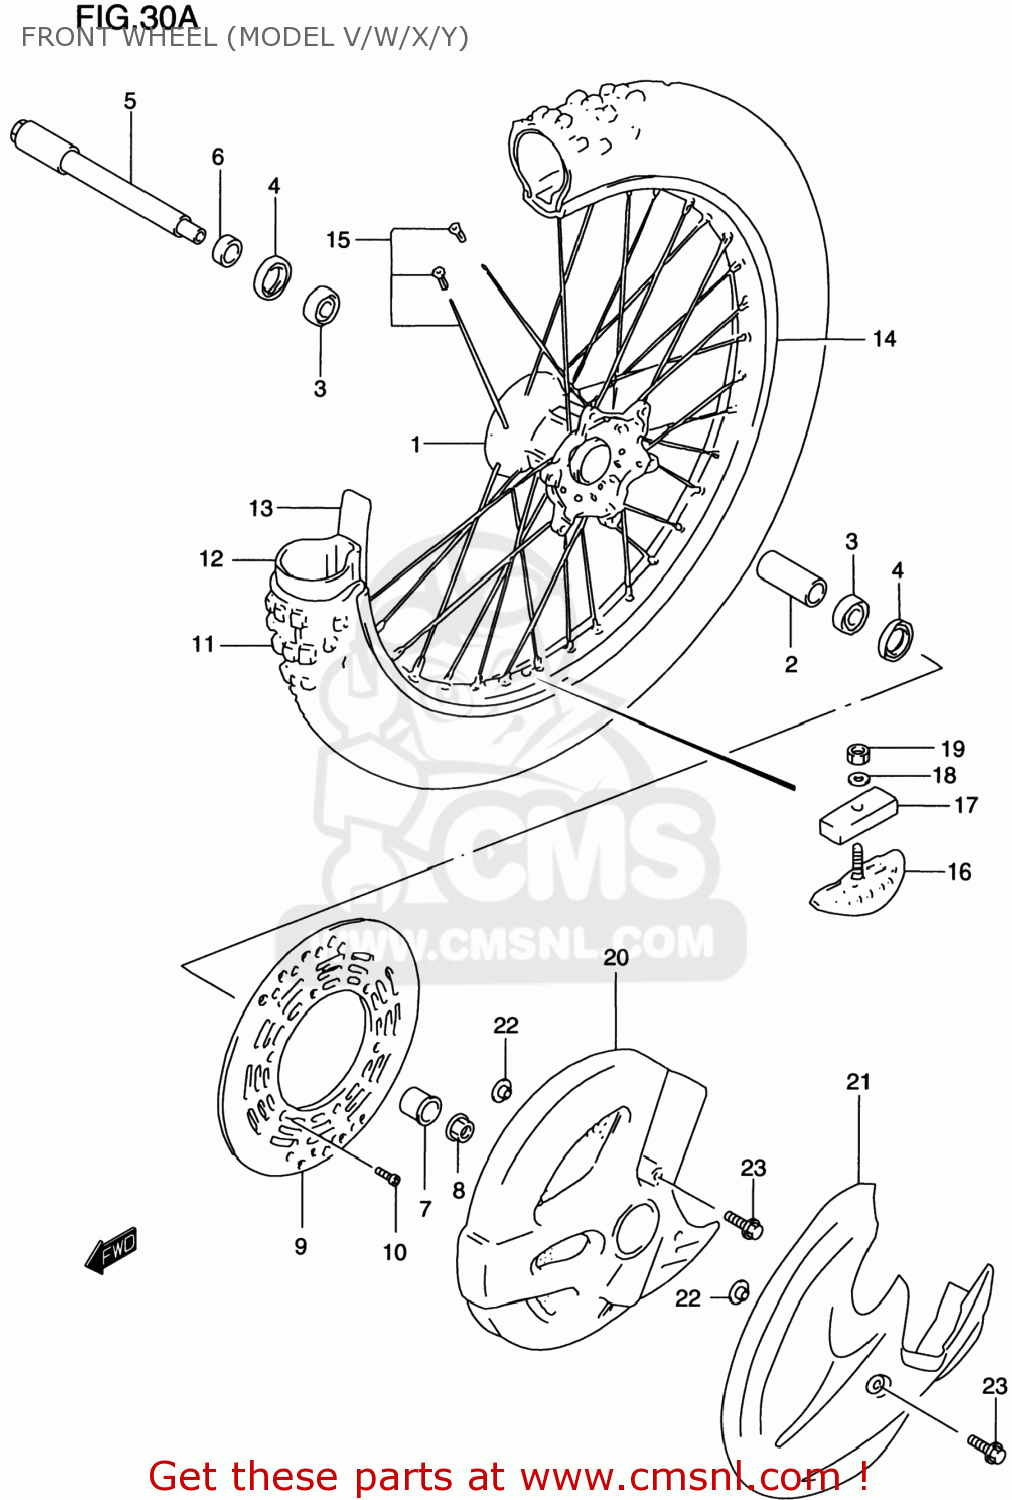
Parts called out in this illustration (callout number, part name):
1	HUB,FR
2	SPACER,FR HUB BEARING
3	BEARING
4	SEAL,OIL(25X37X6)
5	AXLE,FRONT
6	SPACER,FR AXLE,R
7	SPACER,FR AXLE,L
8	NUT
9	DISC,FR BRAKE
10	SCREW
11	TIRE,FRONT 80/100-21
12	TUBE
13	PROTECTOR,WHEEL INNER
14	RIM,FR WHEEL(1.60X21 AL)(.WHT)
15	SPOKE SET,FR WHEEL
16	STOPPER,BEAD
17	CUSHION,BEAD STOPPER
18	WASHER
19	NUT
20	COVER,FRONT BRAKE DISC
21	COVER,FR BRAKE DISC
22	WASHER
23	BOLT(6X16)
